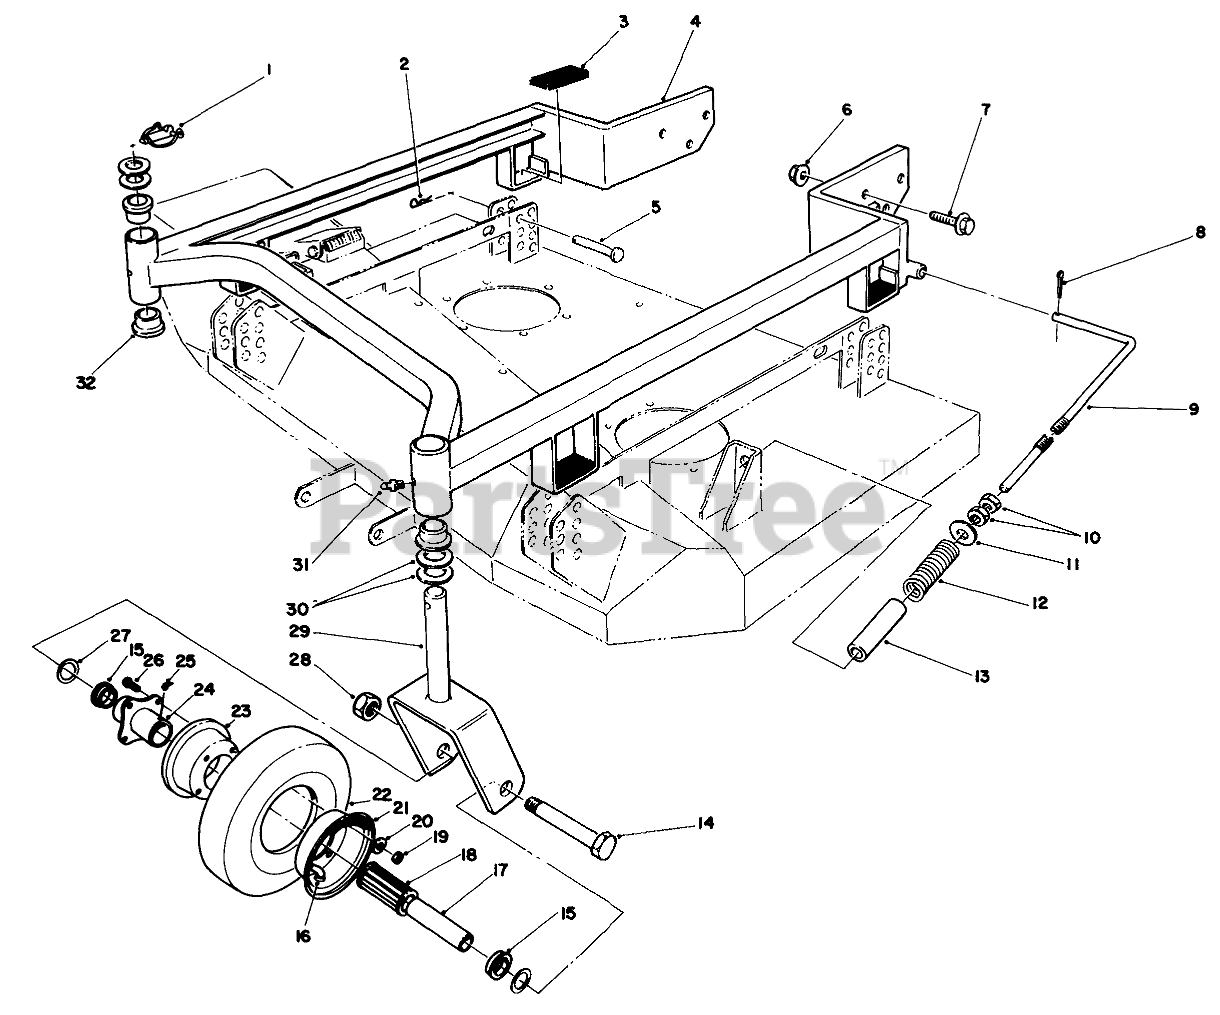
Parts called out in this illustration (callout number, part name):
1	PIN-LYNCH
2	PIN-HAIR
3	Cushion-Rubber
4	Frame-Carrier (Incl. Ref. #32)
5	PIN-CLEVIS
6	NUT-LOCK, FLANGE
7	SCREW-HHF
8	PIN-COTTER
9	ADJUSTING SHAFT
10	NUT-JAM
11	WASHER
12	SPRING-COMPRESSION
13	SLEEVE-TUBE, 36 INCH
14	SCREW-HH
15	RETAINER
16	Bolt-Stud
17	Bushing-Spanner
18	BEARING-ROLLER
19	NUT-HEX
20	WASHER-LOCK
21	WHEEL HALF-MALE
22	TIRE-8 Inch (4-PLY)
23	WHEEL HALF-FEMALE
24	HUB-CENTERED
25	FITTING-GREASE
26	WHEEL BOLT
27	SPACER-WHEEL
28	NUT-LOCK
29	FORK-Castor
30	WASHER-THRUST
31	FITTING-GREASE
32	Bushing
